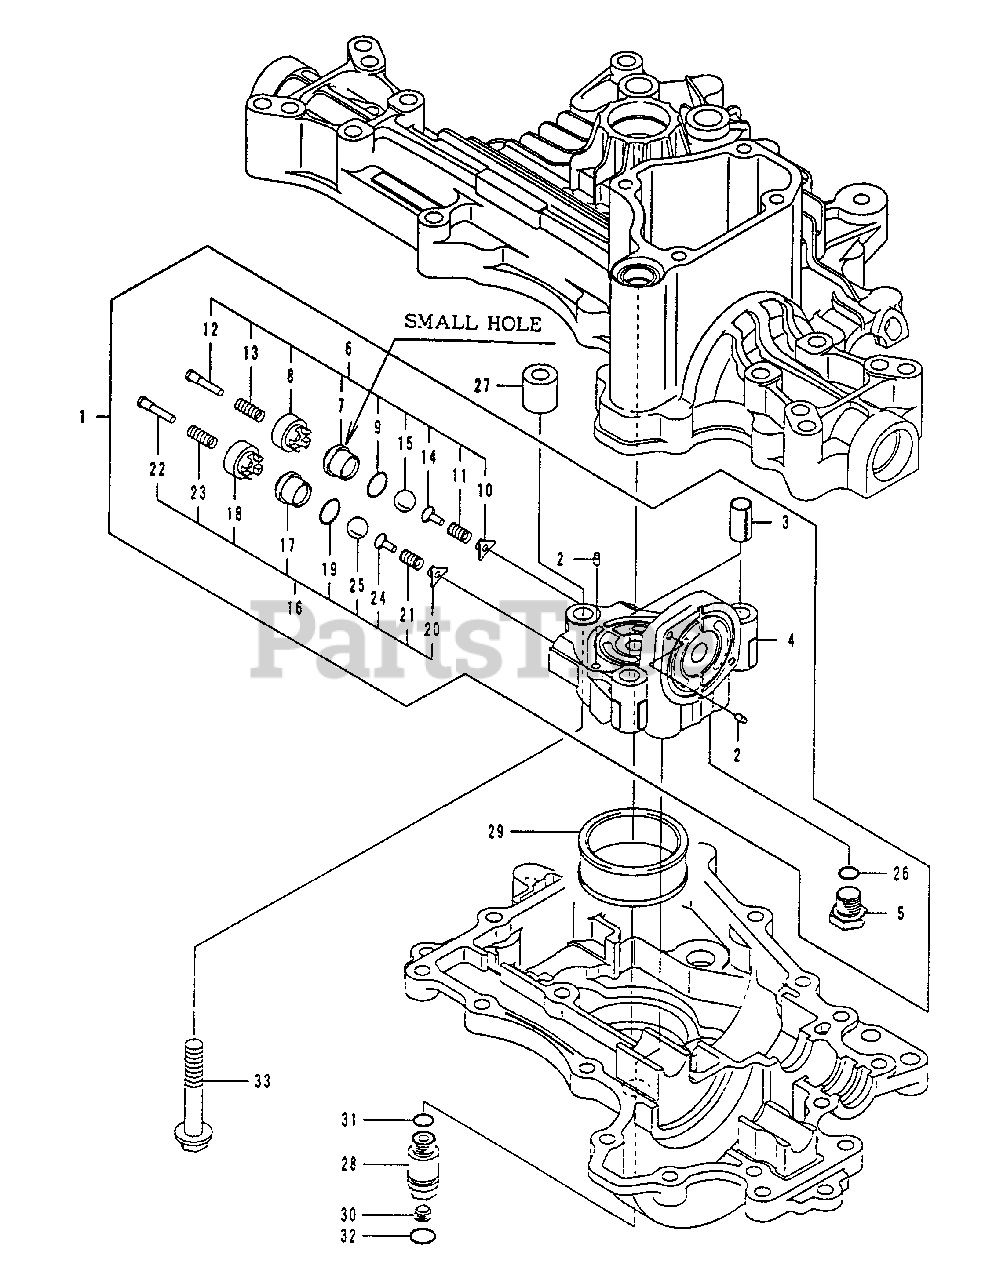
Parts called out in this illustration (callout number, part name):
1	CENTER CASE CMP.
2	KNOCK PIN 3.5
3	KNOCK PIN 12 X 22
4	CENTER CASE
6	VALVE(A-1 SET
7	SLEEVE (A1
8	VALVE(B
9	PACKING 1015
10	HOLDER(BYPASS
11	SPRING
12	PUSH PIN
13	SPRING PUSH PIN
14	HOLDER (BALL
15	BALL 3/8
16	VALVE (A-2 SET
17	SLEEVE (A2
18	VALVE (B
19	PACKING 1015
20	HOLDER(BYPASS
21	SPRING
22	PUSH PIN
23	SPRING PUSH PIN
24	HOLDER (BALL
25	BALL 3/8,
26	PACKING P 11
27	COLLAR 10 X 20 X 20
30	PLUG PT 1/8
31	PACKING P 11
32	PACKING P 14
33	BOLT 10 X 60
